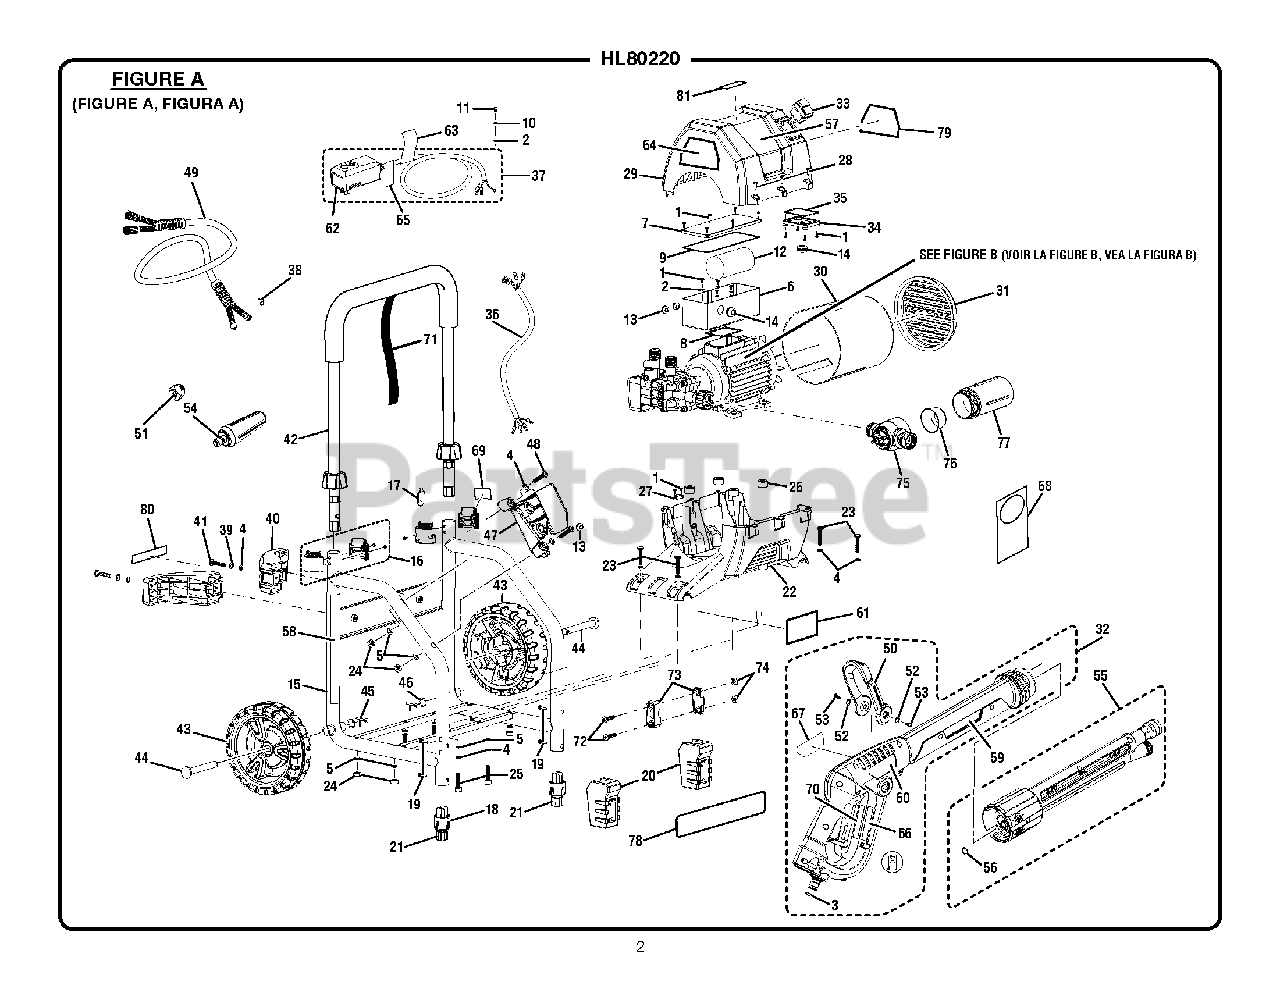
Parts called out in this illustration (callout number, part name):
1	Screw (M10)
2	Washer (M4)
4	Lock Washer (M6)
5	Washer (M6)
6	Electrical Box
7	Electrical Box Cover
8	Upper Electrical Box Gasket
9	Lower Electrical Box Gasket
10	Lock Washer (M4)
11	Screw (M4 x 6 mm)
12	Capacitor
15	Frame (w/Label)
16	Handle Clamp Assembly
17	Handle Release Button
19	Screw (M4 x 18 mm)
20	Foot Cover
22	Lower Housing (w/Label)
23	Screw (M6 x 40 mm)
24	Lock Nut (M6)
25	Screw (M6 x 35 mm)
26	Motor Pad
27	Cord Clamp
28	Screw (M3.5 x 20 mm)
29	Upper Housing (w/Labels)
31	Vent Cover
32	Trigger Housing Assembly (w/Labels)
34	Switch Cover
35	Switch Cover Gasket
36	Wiring Harness
37	Power Cord Assembly
38	Low Pressure Hose Clip
40	Cord Wrap Arm
41	Screw (M6 x 16 mm)
42	Handle Assembly
47	Wand Holder Assembly
48	Screw (M6 x 38)
49	Hose Assembly
50	Low Pressure Trigger
51	High Pressure Nozzle
52	Washer (M6)
53	Screw (M2.9 x 20 mm)
54	Turbo Nozzle
55	Lance Assembly
57	Performance Label
58	Quick Start Label
59	HydroSurge Trigger Handle Label
60	Trigger Handle Logo Label
61	Data Label
62	GFCI Reset Label
63	Warning Label (UL)
64	Danger Label
65	California Proposition 65 Label
66	Trigger Handle Specifications Label
67	Trigger Handle Warning Label
68	G-Clean Hang Tag
69	Handle Release Label
70	Wand Warning Label (FR/SP)
71	Hose Strap
72	Clamp screw
73	G-Clean Clamp
74	Clamp nut
75	G-Clean Assembly
76	Mesh Filter
77	Detergent Container
78	Front Panel Label
79	Danger (FR)
80	Homelite Inquires Label
81	Hydrosurge Label
